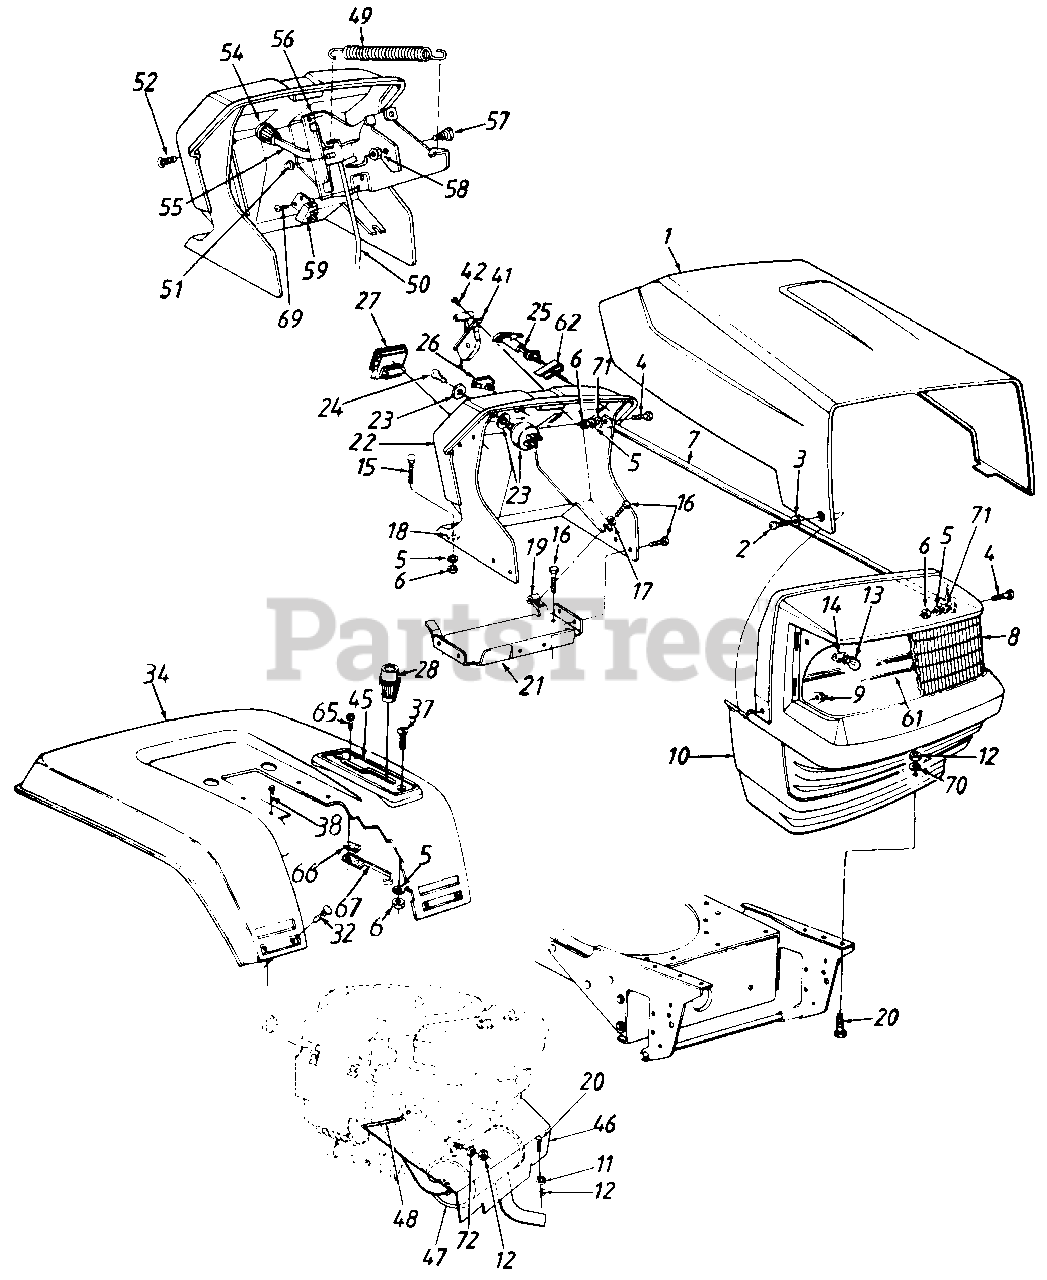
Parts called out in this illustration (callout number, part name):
3	Spr. Wash. .265" I.D. x .562" O.D.
4	Hex Bolt 1/4-20 x 62" Lg.
5	L-Wash. 1/4" I.D.
6	Hex Nut 1/4-20 Thd.
9	Flange L-Nut 1/4-28 Thd.
10	Grille
11	L-Wash. 5/16" I.D.
12	Hex Nut 5/16-18 Thd.
13	Lamp
14	Socket
15	Carriage Bolt 1/4-20 x 1.0" Lg.
16	Hex AB-Tap Scr. 1/4 x .62" Lg.
17	Fl-Wash. .281" I.D. x .73" O.D.
18	Bolt Retainer 1/4" I.D.
19	Speed Nut 1/4-20 Thd.
20	Hex Bolt 5/16-18 x .75" Lg.
23	Ignition Switch
24	Ignition Key
25	Choke Control
26	Light Switch
27	Ammeter
28	Shift Knob
32	Carriage Bolt 1/4-20 x .5" Lg.
38	Hex Wash. Hd. AB-Tap Scr. 5/16 x .75" Lg.
42	Truss Mach AB-Tap Scr. #10 x .5" Lg.
45	Speed Selector Plate
46	Front Heat Shield
47	Muffler
48	Trim Strip 12" Lg.
49	Ext Spring 5.06" Lg.
50	Deck Control Rod
51	Speed Nut 1/4" Rod
52	Torx Mach. Scr. 1/4 x .62" Lg.
54	PTO Knob
55	PTO Lever
56	PTO Bracket
57	Shld. Bolt .437" Dia. x .162"
58	Hex L-Nut 5/16-18 Thd.
59	Safety Switch (PTO)
61	Grille Reflector Label
62	Retainer Clip
65	Hex Wash. Hd. AB-Tap Scr. #8 x .5" Lg.
66	Insulator Nut Plate
67	Reverse Safety Switch
69	Hex Wash. Hd. B-Tap Scr. #10 x .38" Lg.
70	Fl-Wash. .344" I.D. x 1" O.D.
71	Fl-Wash. .28" I.D. x .75" O.D.
72	Spec L-Wash 5/16" I.D.
